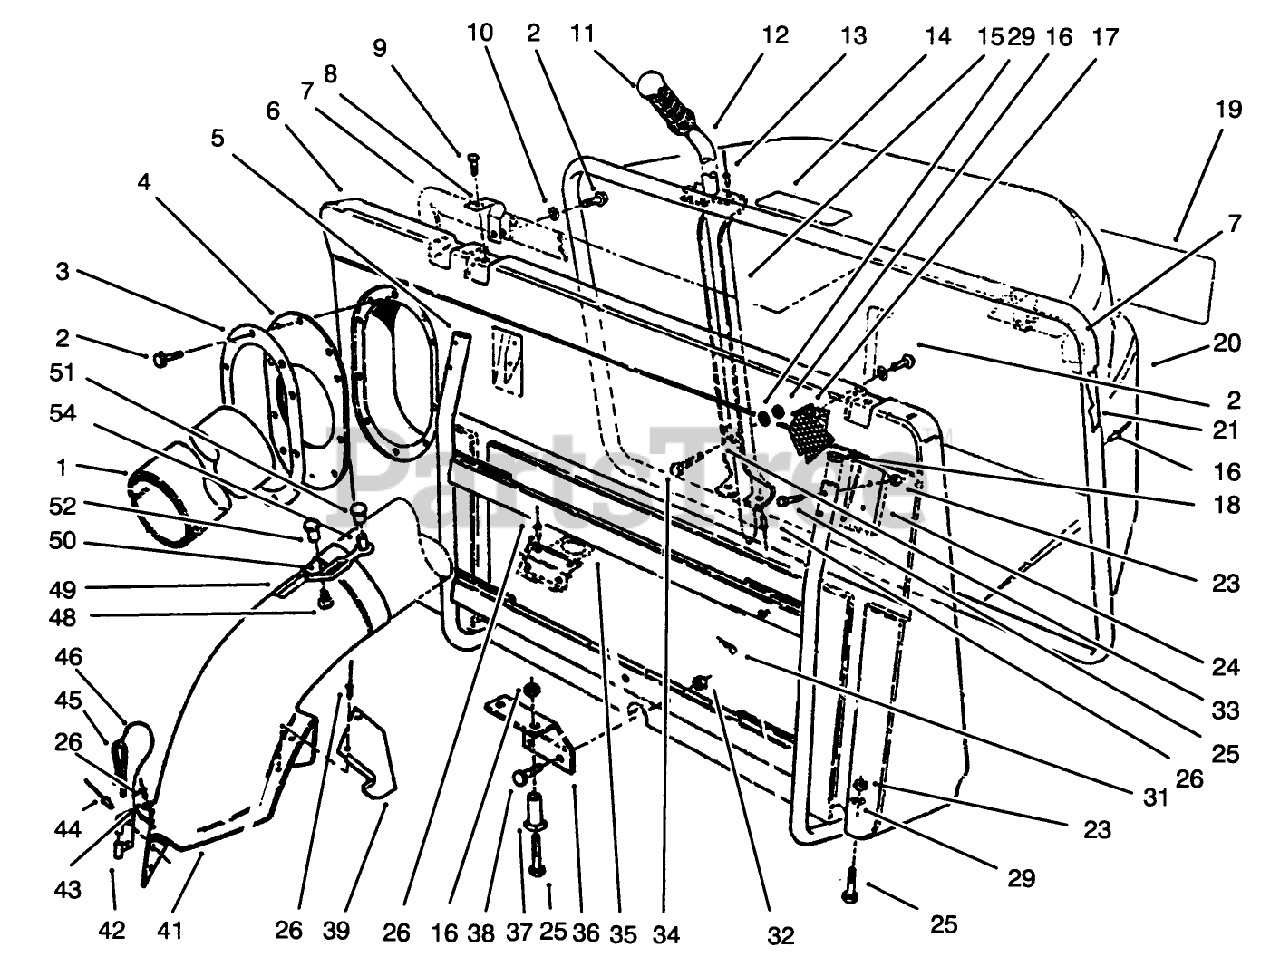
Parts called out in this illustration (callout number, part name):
1	GRASS DISCHARGE TUBE
2	SCREW-HWHTF
3	RING-RETAINING
4	RING-RETAINER, RUBBER
5	Frame
6	BAG-FRONT
7	SEAL-BAG
8	Bracket-Hinge
9	SCREW-HH
10	WASHER-FLAT
11	GRIP-HANDLE
12	HANDLE-DUMP
13	RIVET-POP
14	DECAL - WARNING
15	Channel-Dump Handle
16	NUT-LOCK, NI
17	Screen Bag
19	DECAL-BAG, EASY EMPTY
20	BASKET-GRASS
21	Frame-Grass Basket
23	NUT-LOCK, NI
24	Plate-Backup
25	SCREW-HH
26	RIVET-BLIND
29	WASHER-FLAT
31	PIN-HAIR
32	NUT-LOCK, NI
33	GUIDE-HANDLE, DUMP
34	SCREW-HH
35	Latch
36	Bracket-Hitch
37	Spacer
38	SCREW-HH
39	CHUTE SUPT BRKT
41	Chute Ass-y. (Incl. Ref.#26, 39, 42-46, 48, 49, & 52)
42	BRACKET-MOUNTING, CHUTE
43	WASHER-PLAIN
44	RIVET-BLIND
45	PIN-LOCKING, CHUTE
46	LANYARD
48	SCREW-HWH
49	DECAL-DANGER
50	RETAINER-DUCT
51	SPACER-INTERLOCK
54	FASTENER-PANEL
